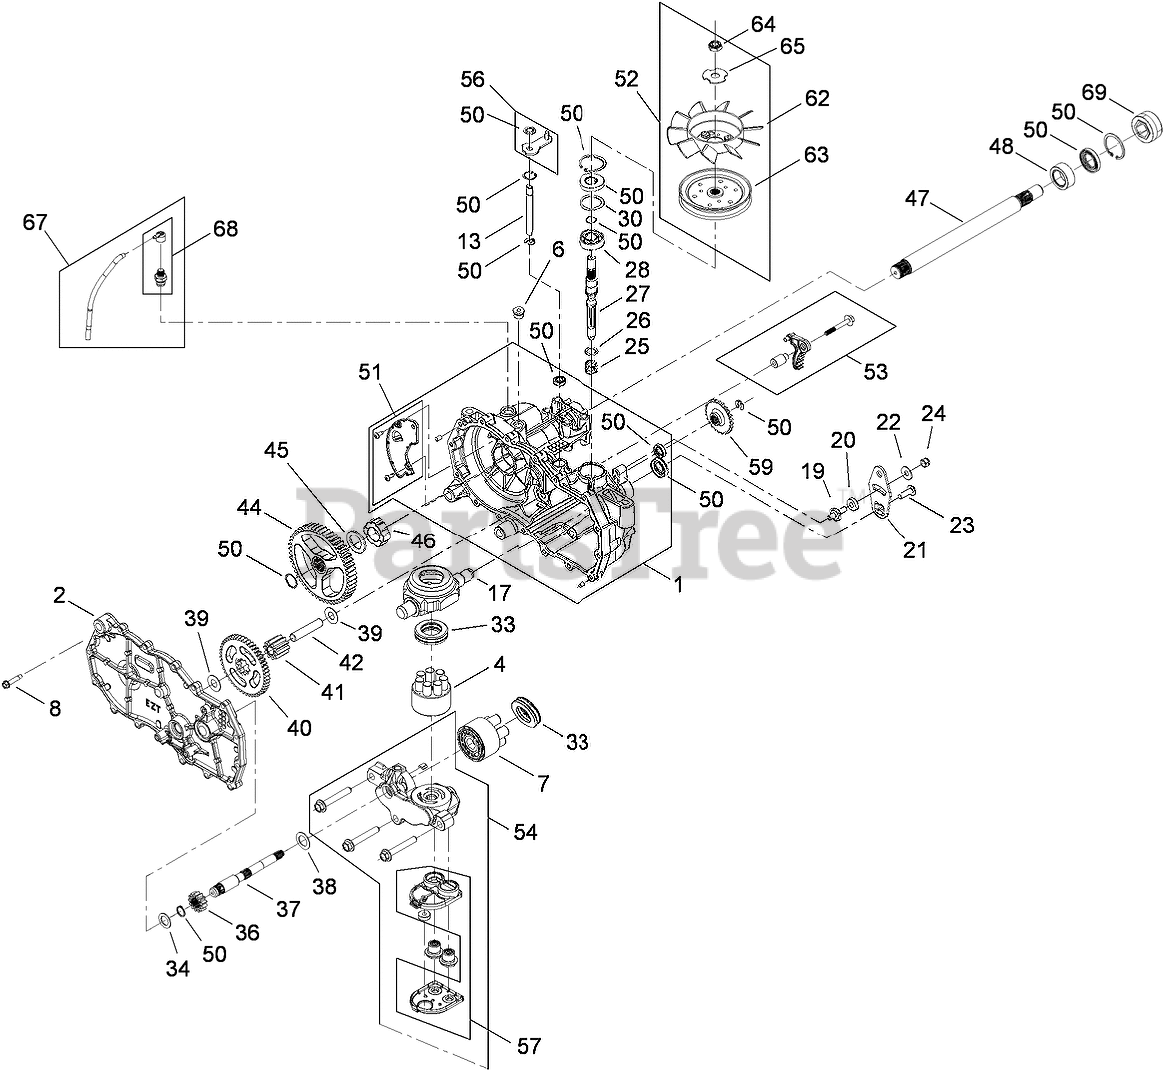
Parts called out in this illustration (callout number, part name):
1	LH MAIN HOUSING ASM
2	LH SIDE ASM
4	PUMP BLOCK ASM
6	PLUG-THREAD, STRAIGHT
7	CYLINDER BLOCK KIT
8	SCREW-HHF
13	ROD-BYPASS
17	SWASHPLATE-TRUNNION
20	PUCK-FRICTION
21	ARM-CONTROL
22	WASHER-PIVOT
25	SPRING-BLOCK
26	WASHER-THRUST
27	SHAFT-INPUT
28	BEARING-BALL
30	SPACER
33	BEARING-THRUST
34	WASHER-FLAT
36	GEAR-PINNION, 13T
37	SHAFT-MOTOR
38	WASHER
39	WASHER
40	GEAR-10T/48T
41	GEAR-JACKSHAFT, 10T
42	PIN-JACKSHAFT
44	GEAR-52T, BULL
45	WASHER
46	BEARING-SLEEVE
47	SHAFT-AXLE
48	BUSHING-AXLE
50	SEAL KIT
51	EXPANSION PLATE KIT
52	Fan Pulley Kit
53	BRAKE ARM KIT
54	CENTER SECTION FILTER KIT
56	BYPASS ARM KIT
57	FILTER KIT
59	DISC-BRAKE, COG
62	FAN-6 INCH, 10 BLADE
63	PULLEY
64	NUT-LOCK
65	WASHER-SLOTTED
67	BREATHER KIT
68	BREATHER ASM
69	COVER-NUT, AXLE
